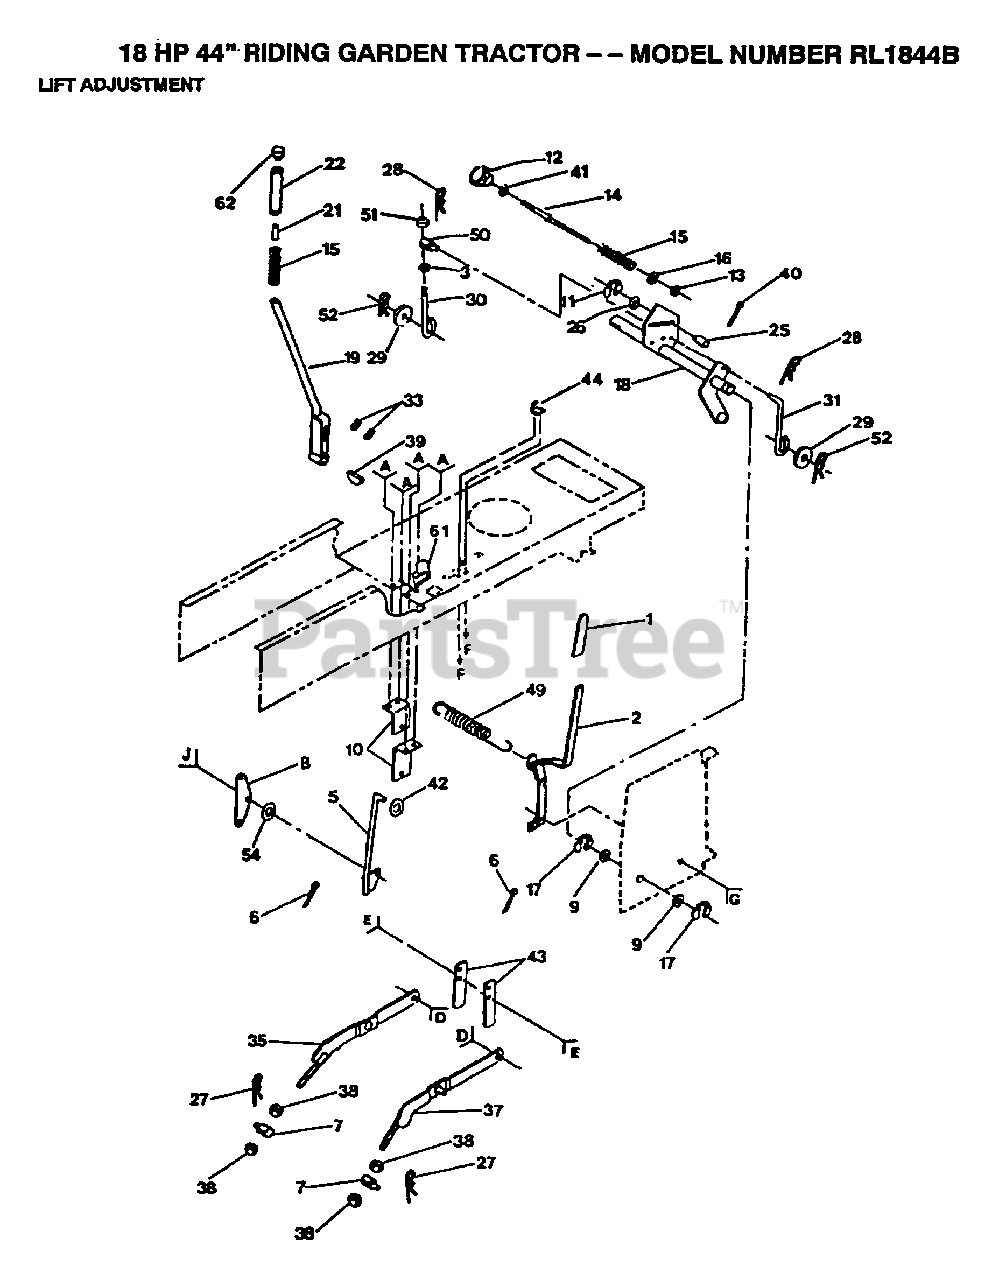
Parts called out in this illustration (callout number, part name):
5	ROD ASSEM YT
6	COTTER PIN
8	"T, BELLCRANK"
9	WASHER
10	"BRKT,BELLCRAN T"
11	KLIP RING
13	NUT T
14	ROD LIFT LT
15	SPRING T
16	WASHER
17	E-RING
22	GRIP
23	BOLT LT
25	TRUNION LT
26	WASHER
27	SPRING H
30	PIVOT PIN T
31	LIFT LINK LT
35	LH SUSP ARM ASM
36	"BOLT, SHOULDER LT"
37	RH SUSP ARM ASM
38	NUT
41	NUT
42	WASHER
43	UPSTOP
44	BRACKET LT
45	SCREW
49	"SPRING.EXT.8.5"""
51	NUT
52	SPRING.RETAINER
54	WASHER
55	WASHER T
56	NUT SPECIAL T
59	WASHER
